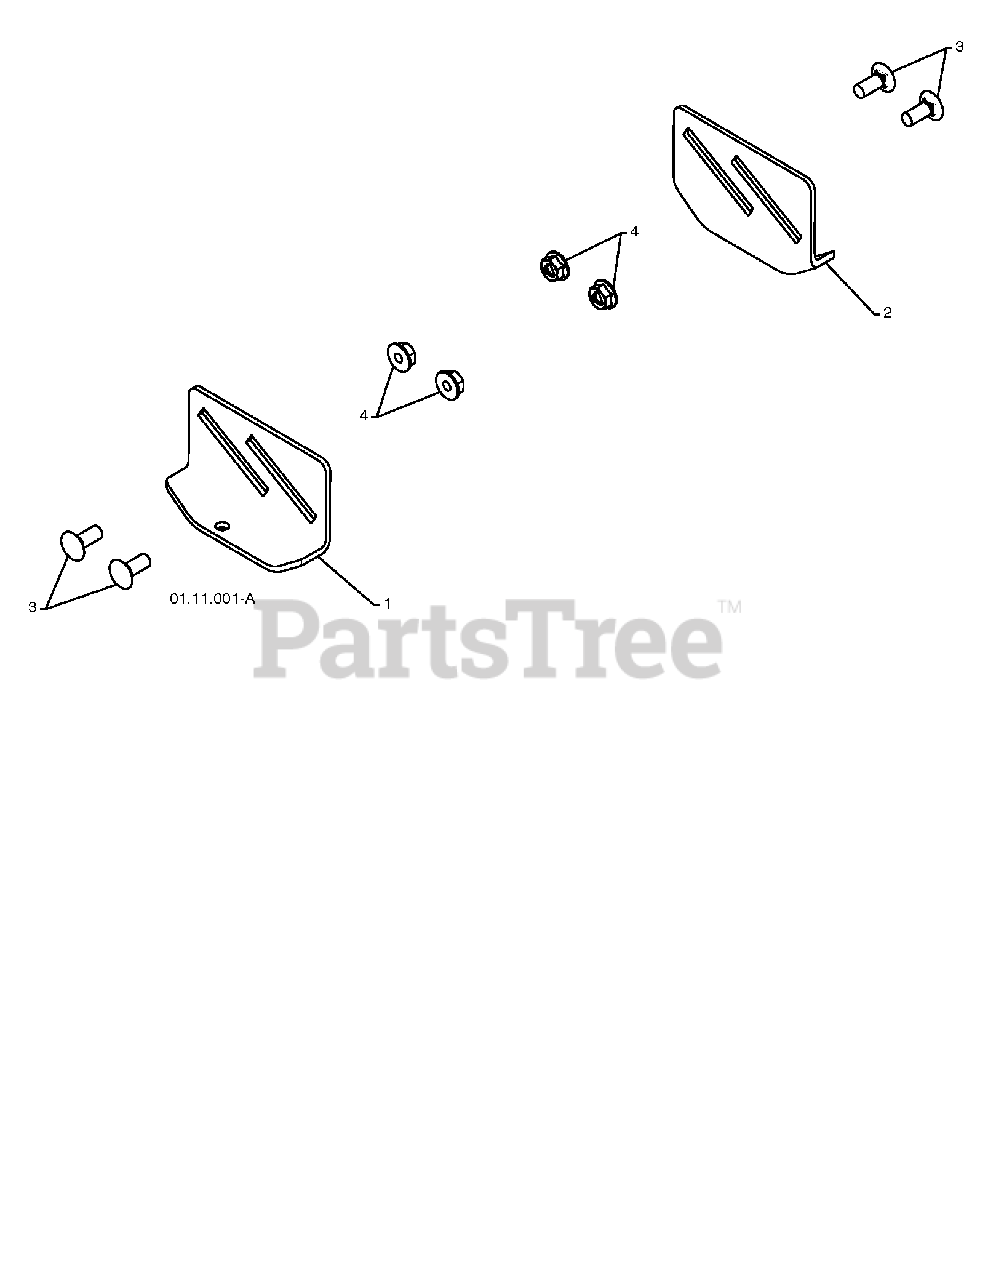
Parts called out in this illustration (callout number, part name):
1	SKID PLATE LH
2	SKID PLATE RH
4	NUT, LOCK 5/16-18
